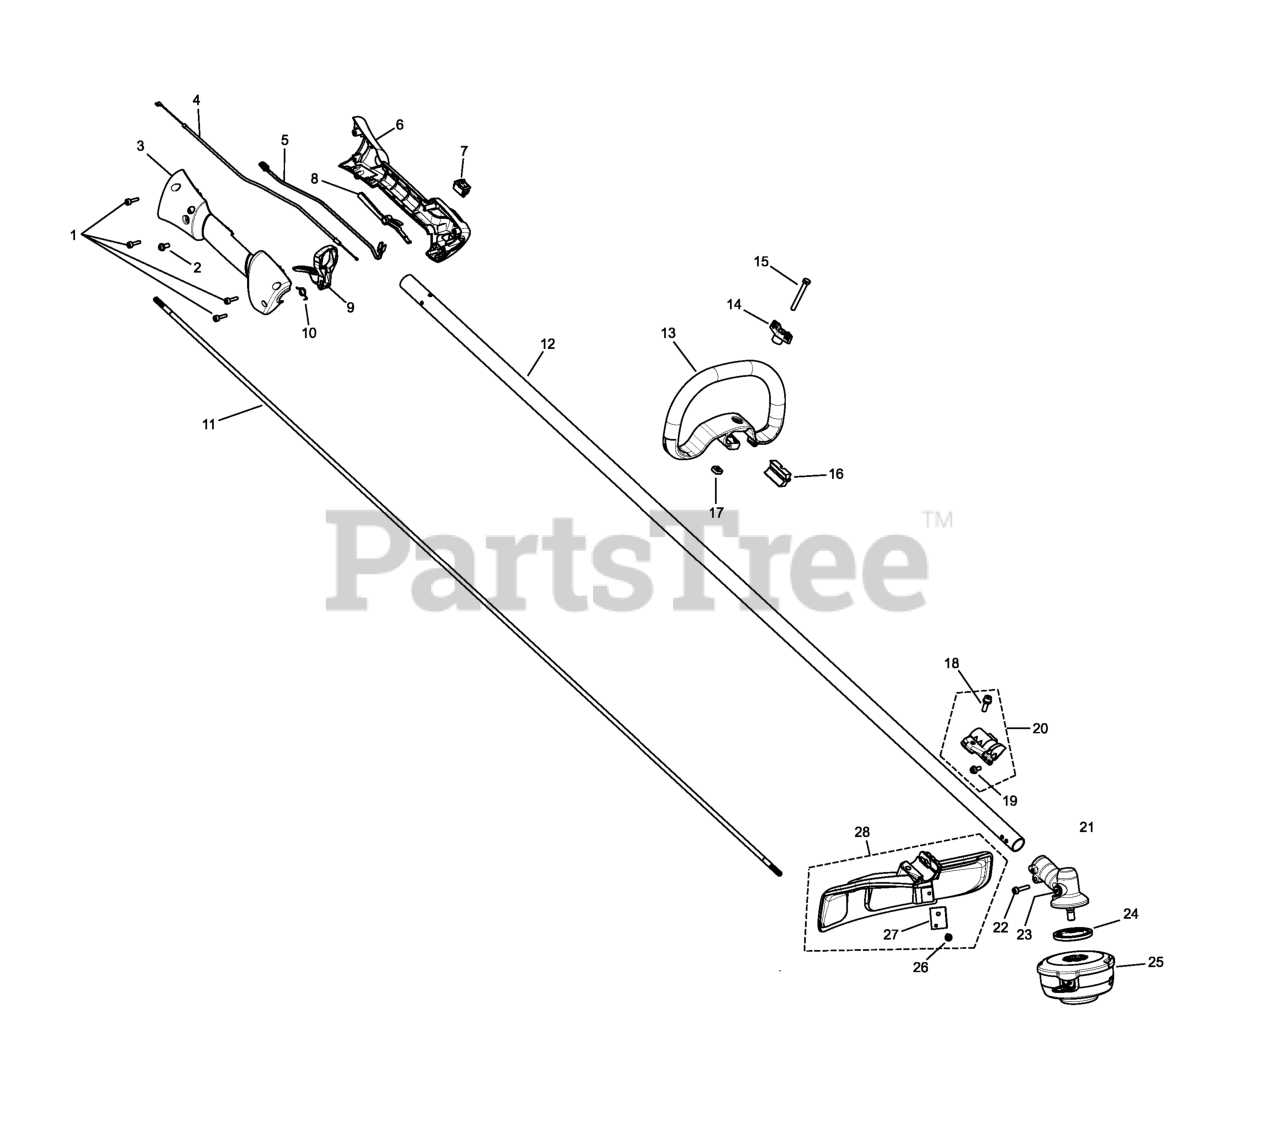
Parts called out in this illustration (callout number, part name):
1	SCREW
2	SCREW
3	HSG RH THRTTL HVA 24MM WL ORG
4	ASSY THROTTLE
5	CABLE SHORT CIRCUIT HND
6	HSG LH THRTTL HVA 24MM ORANGE
7	SWITCH
8	THROTTLE LOCKOUT HVA ORANGE
9	TRIGGER THROTTLE HVA ORANGE
10	SPRING TRIGGER
11	DRIVESHAFT 525L
12	KIT SVC 325L DRIVESHAFT
13	HANDLE
14	KNOB
15	SCREW M6X50
16	SPACER PLASTIC
17	NUT
18	BOLT
19	BOLT
20	ASSY CLAMP 523L
21	GEARHEAD
22	SCREW
23	PLUG
24	DRIVE DISC
25	TRIMMER HEADS
26	SCREW ITXSCFT PW4.8X16 T27 CH
27	LINE CUTTER
28	TRIMMER GUARD 323L MFL.
